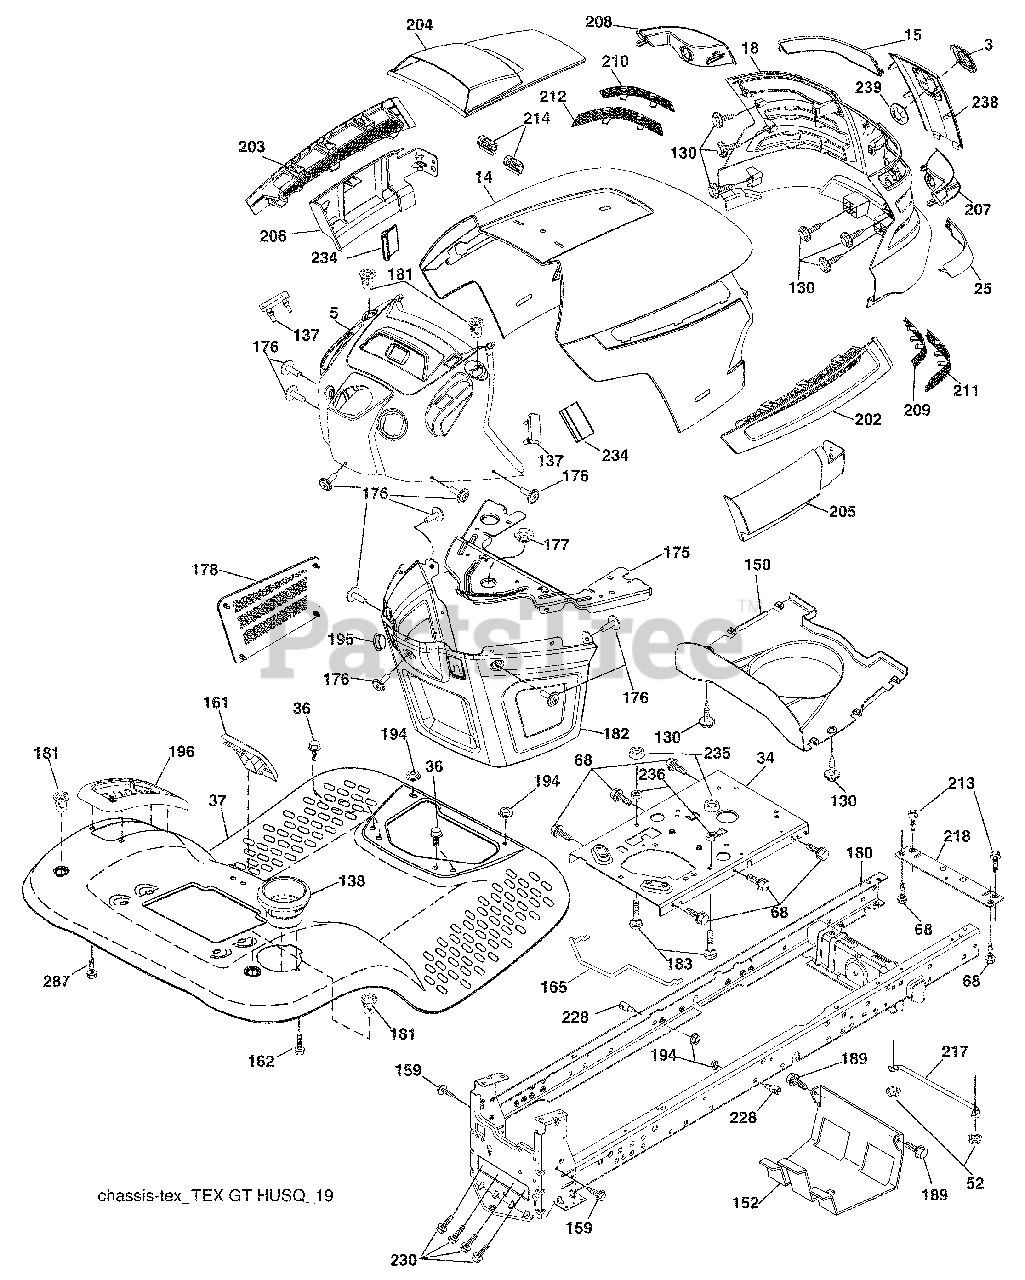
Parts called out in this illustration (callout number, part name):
3	Trim, Husq.
4	Logo
14	Hood
18	Grille/Lens Asm.
34	Plate Engine
36	Screw 5/16-18 x 3/4
52	Nut Lock 5/16-18
68	Screw Thdrol 5/16-18 x 1/2
130	Screw #10 x 0.750 BOS Thread
137	Bumper Dash
138	Cupholder
152	Shield Browning
161	Window Fuel
165	Support Tank
175	Crossmember
176	Screw 10-24 x 5/8
177	Bushing Steering
178	Cargo Net Asm.
180	Chassis
181	Bushing Mtg. Fender Crgo
182	Dash Lower
183	Bolt Fin Hex 5/16-18 unc x 1-1/4
189	Screw 5/16-18 x 3/4
194	Nut Lock Hex Flange 5/16-18
195	Plug Hole Dash Lower
196	Console Asm. Deck Lift
202	Vent Side Hood RH
203	Vent Side Hood LH
204	Vent Top Hood
205	Skirt Hood Side RH
206	Skirt Hood Side LH
209	Insert Hex Top RH
210	Insert Hex Top LH
211	Insert Hex Bottom RH
212	Insert Hex Bottom LH
213	Bolt 5/16-18 x 3/4
214	Clip Retainer Tinner
218	X-Piece Hood Stop
228	Stud Fastner
230	Bolt Shoulder 5/16-18
234	Bumper Hood
235	Spacer Fender
236	Nut Lock 5/16-18 unc
287	Screw 1/4-20 x 3/8
